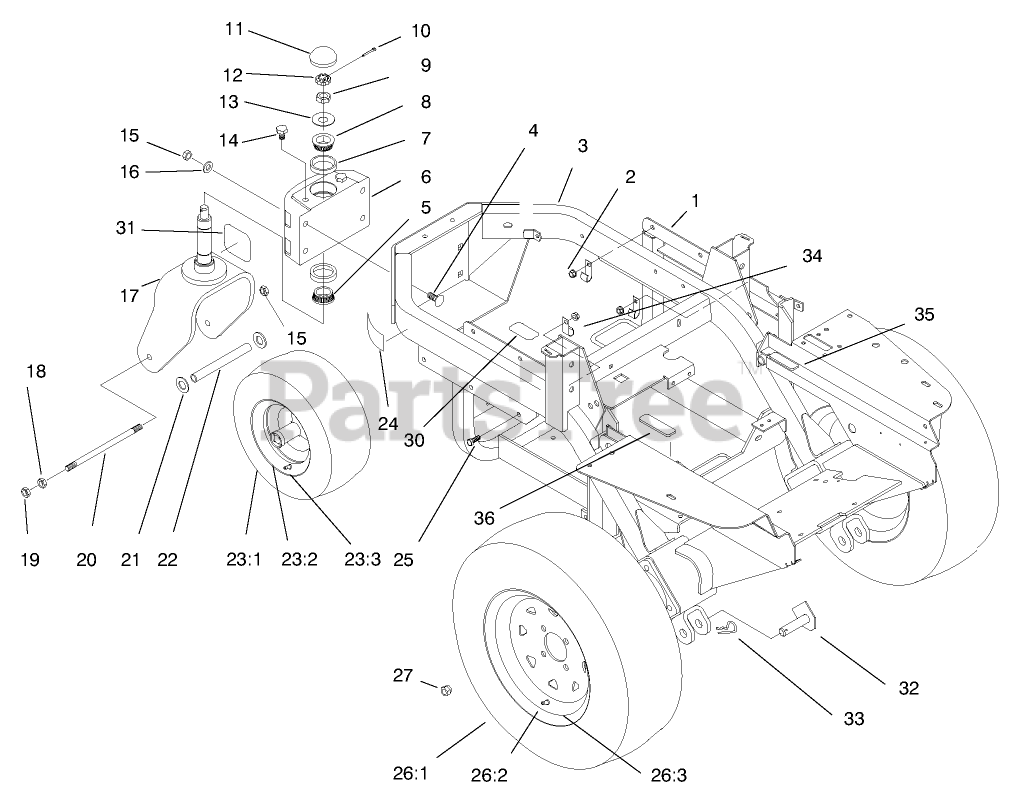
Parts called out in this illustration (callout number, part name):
1	ENGINE SUPPORT ASM
2	NUT-LOCK, NI
3	FRAME ASM W/ DECALS
4	SCREW-CARR
5	BEARING-CONE
6	HOUSING - SPINDLE
7	CUP-BEARING, ROLLER
8	BEARING-ROLLER, CONE
9	NUT-JAM
10	PIN-COTTER
11	DUSTCAP
12	NUT-LOCK, RETAINER
13	WASHER-FLAT
14	SCREW-HH
15	NUT-LOCK, NI
16	WASHER-FLAT
17	CASTER FORK ASM
18	SCREW-HH
21	WASHER-FLAT
22	TUBE-SPACER, CASTOR
23:2	WHEEL ASM
23:3	STEM-VALVE
24	DECAL-HOT SURFACE
25	SCREW-HH
26:1	Tire
26:2	STEM-VALVE
26:3	WHEEL
27	NUT-LUG
28	RIVET-BLIND
31	DECAL - Z325
32	PIVOT PIN ASM
33	PIN-HAIR
34	CLIP
35	PAD-RUBBER
36	DECAL-WARNING
